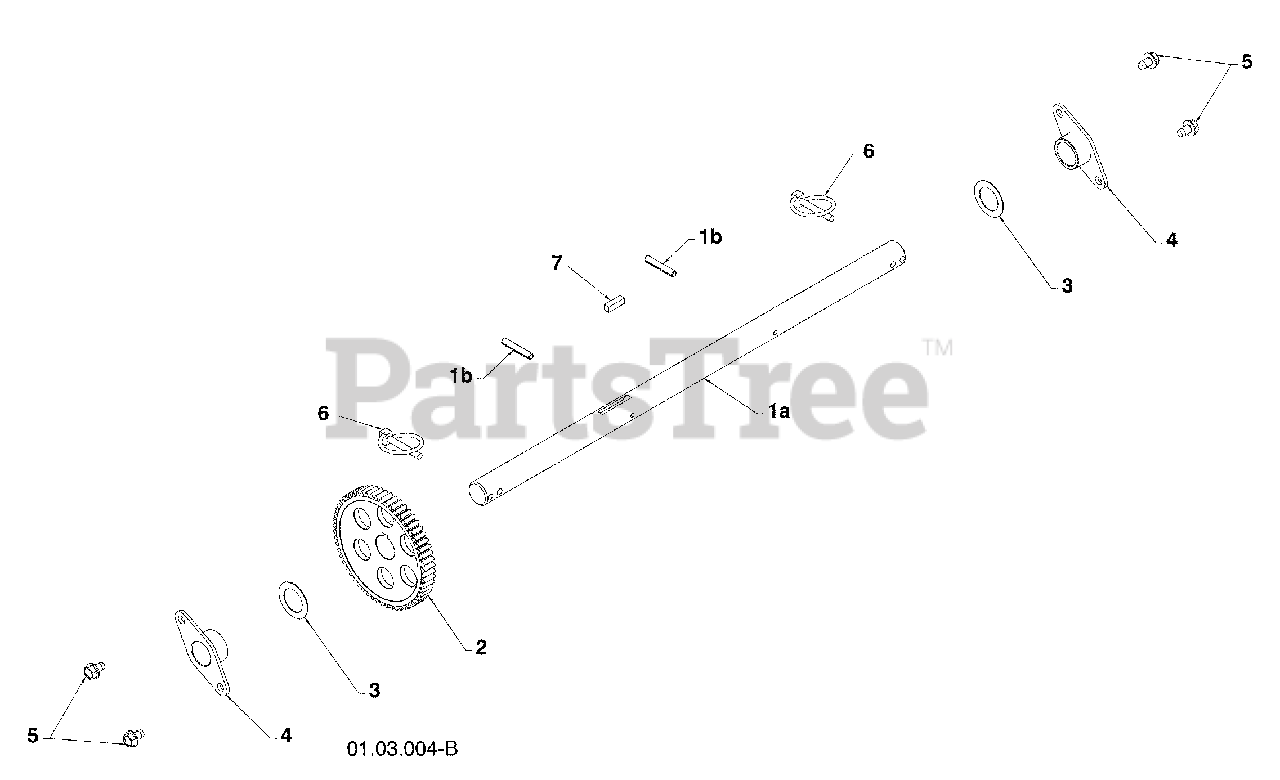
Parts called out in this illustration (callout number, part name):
1	AXLE ASSEMBLY (assy of 1a,1b)
2	GEAR
3	THRUST WASHER
5	BOLT 5/16-18 X .500
7	SQUARE KEY
